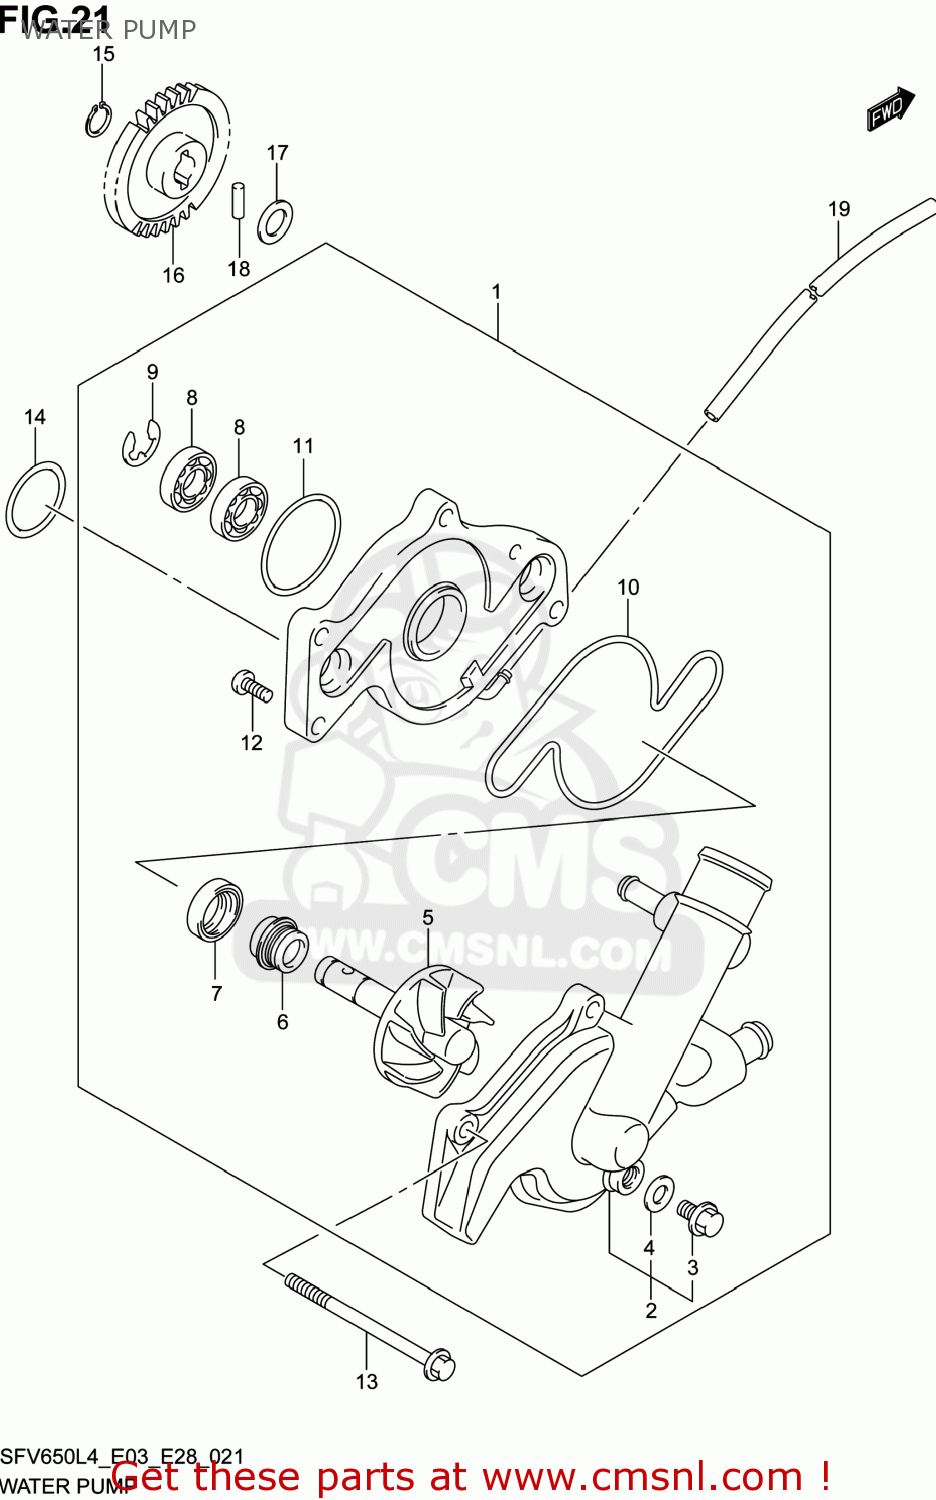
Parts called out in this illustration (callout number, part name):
1	PUMP ASSY,WATER
2	CASE,WATER PUMP
3	BOLT,DRAIN
4	GASKET(8.2X14X1) (NAS)
5	IMPELLER/SHAFT
6	SEAL,MECHANICAL
7	SEAL,OIL
8	BEARING(10X26X8)
9	E RING
10	O RING
11	O RING,WATER PUMP HOLDER
12	SCREW
13	BOLT(6X70)
14	O RING(D:2.4,ID:21.8)
15	CIRCLIP
16	GEAR,WATER PUMP DRIVEN
17	SHIM(10X18X0.5)
18	ROLLER(4X13.8)
19	HOSE(3.5X6.5X600)
